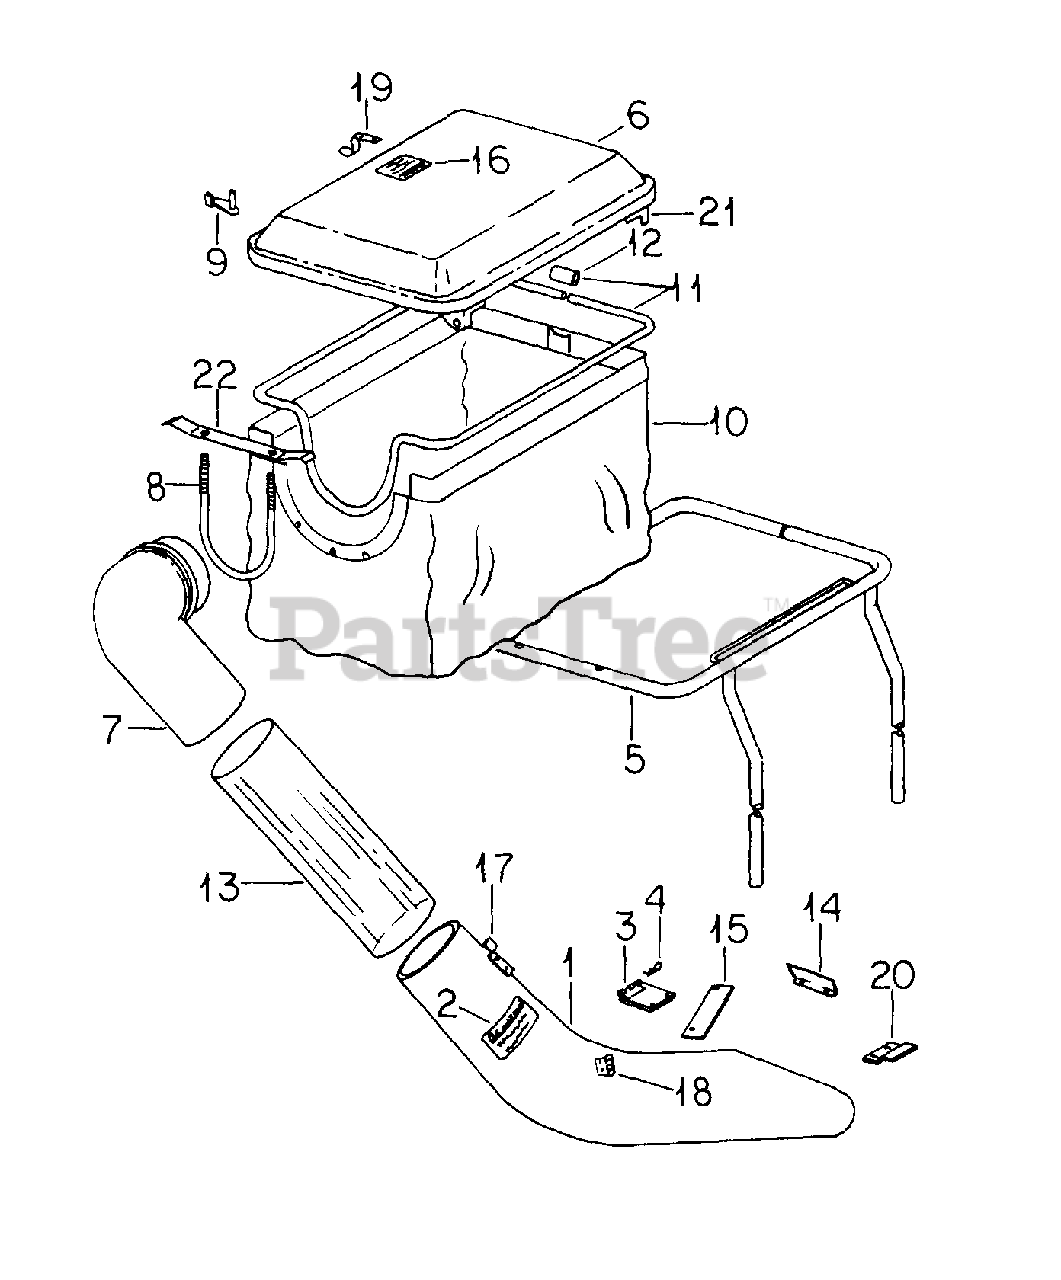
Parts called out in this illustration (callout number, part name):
1	CHUTE ASSY, DISCHARGE
2	PRODUCT GRAPHIC, CAUTION - GRASS CATCHER
3	HINGE ASSY, CHUTE
4	PIN, .094 X 2.402 AND CAD QA COT.
5	FRAME ASSY, BAGGER
6	COVER ASSY, GRASS BAG -DOME TYPE-
7	ELBOW, CHUTE
8	BRACKET, ELBOW
12	SLEEVE, BAG FRAME
13	SHEET, CONNECTING TUBE
14	WING, 28 IN. MOWER BLADE
15	FLANGE, LOCATOR
16	PRODUCT GRAPHIC, CAUTION - MOWER INSTRUCTIONS
17	RETAINER, TUBE
18	HINGE, LEAF CHUTE
20	SUPPORT, FRONT LOCATOR
21	HINGE, COVER
22	SPRING, BAG RETAINER
